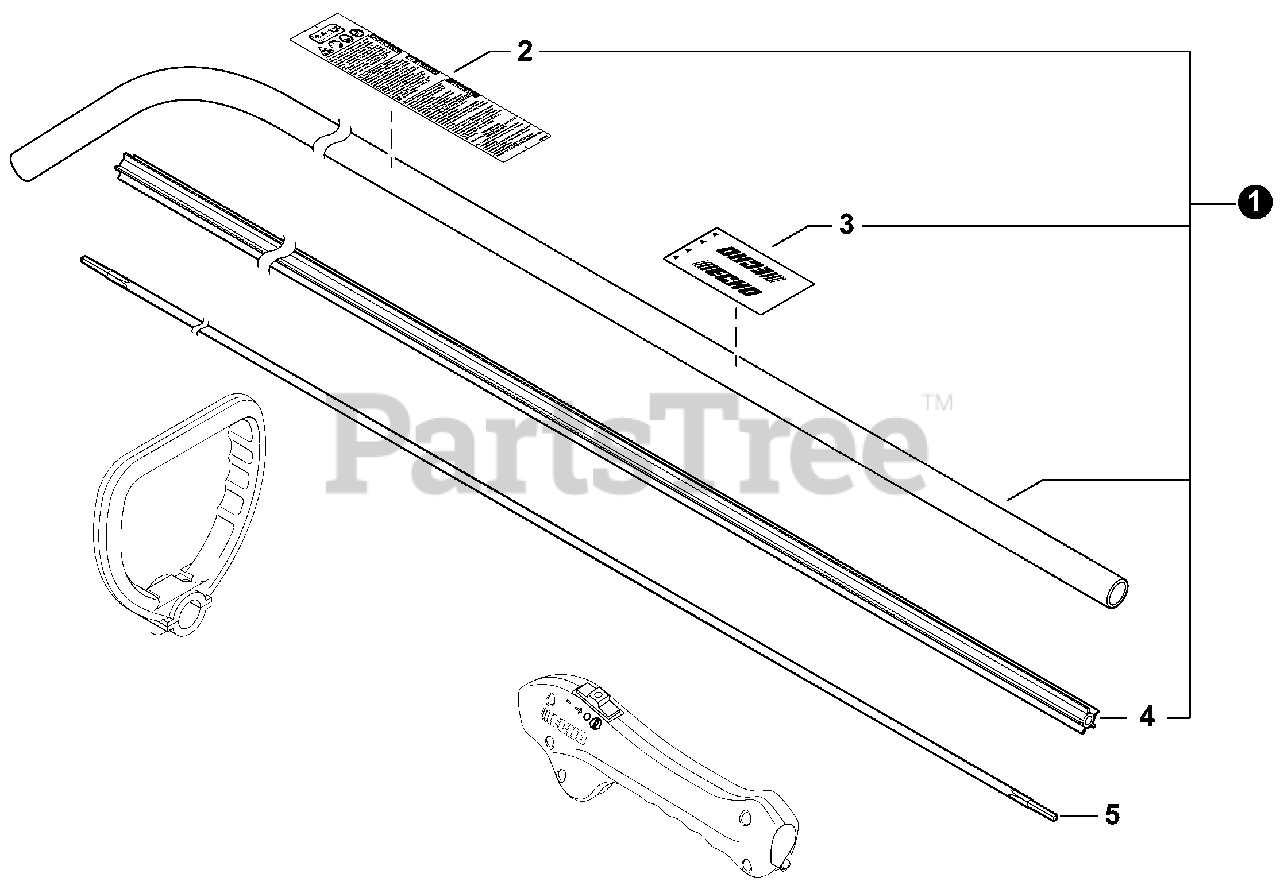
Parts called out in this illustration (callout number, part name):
1	MAIN PIPE ASSY
2	LABEL, CAUTION
3	LABEL, HANDLE LOCATION
4	LINER - FLEXIBLE
5	DRIVESHAFT - FLEXIBLE
